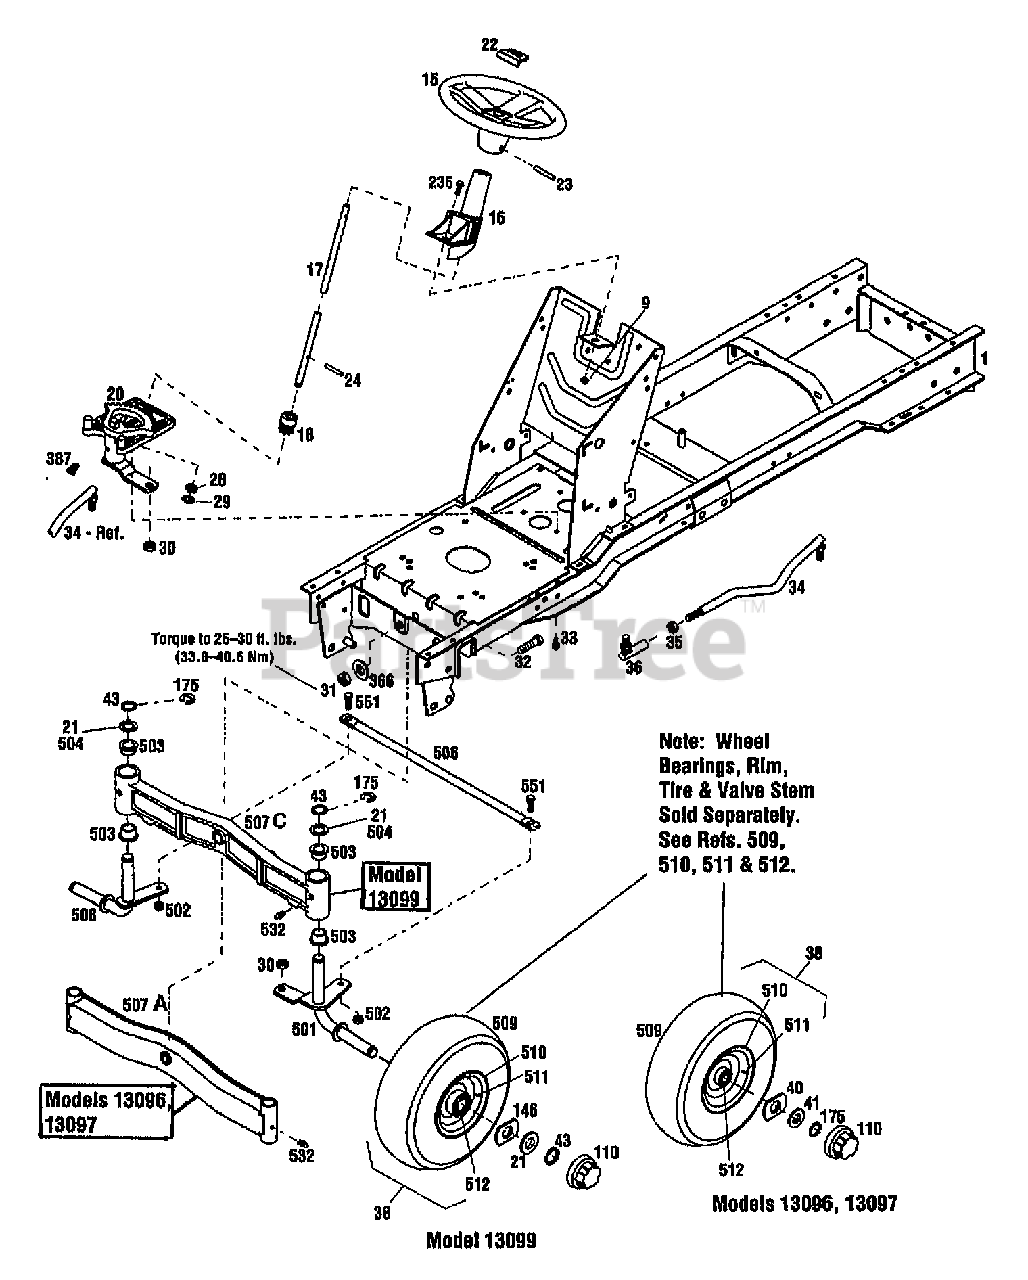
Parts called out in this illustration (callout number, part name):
1	ASSM-FRAME LTX {13096/097}
1	ASSM-FRAME {13099}
9	NUT-HFLK 5/16-18 ZP
15	WHEEL-STEERING
16	SUPPORT-STEERING SHAFT
17	SHAFT-STEERING
18	GEAR-PINION
20	ASSM-STEERING GEAR
21	WASHER-THRUST {13096,13097}
21	WASHER-THRUST {13099}
22	CAP-STEERING
23	PIN-ROLL .25X2.25
24	PIN-ROLL 1/4 X 1-1/4
28	WASHER-1.0X.64X.09
29	RING-RETAINING
30	NUT-HEX/JAM 1/2-20
31	NUT-H/LK 5/8-11
32	SCR-HH
33	SCR-HFLK 5/16-18X.75
34	LINK-DRAG
35	NUT-JAM
36	JOINT-BALL
38	ASSM-WHEEL & TIRE FRONT {13096,13097}
38	ASSM-WHEEL & TIRE FRONT {13099}
40	WASHER-SPEC .75X2.50
41	WASHER-1.38 X.765X .06 ZP
43	RING-HEAVY EXT HD 1.0 ID {13099}
110	CAP-HUB
146	WASHER-SPECIAL .75X2.5
175	RING-RET."E".577 ID
236	SCR-HFLK 5/16-18X.75 ZP
366	WASHER-1.75X.687X.134 ZP
387	FITTING-GREASE 90 DEGREE
501	ASSM-SPINDLE LH {13096/097}
501	SPINDLE-WHEEL LH {13099}
502	NUT-LOCK
503	BUSHING {13096/097}
503	BEARING-FLANGE {13099}
504	WASHER-1.25X.765X.049
506	KIT-TIE ROD W/HDW
507	AXLE-FRONT {13096/097}
507	AXLE-FRONT {13099}
508	ASSM-SPINDLE WHEEL RH {13096/097}
508	SPINDLE-WHEEL RH {13099}
509	TIRE 15X6.00-6RS {13096/097}
509	TIRE-16X6.50-8 {13099}
510	DISC WHEEL {13096/097}
510	RIM-WHEEL {13099}
511	STEM-VALVE
512	BEARINGS-WHEEL {13096/097}
512	BEARING-BALL {13099}
532	FITTING-GREASE 1/4-28X2.00
551	SCR-SHOULDER
